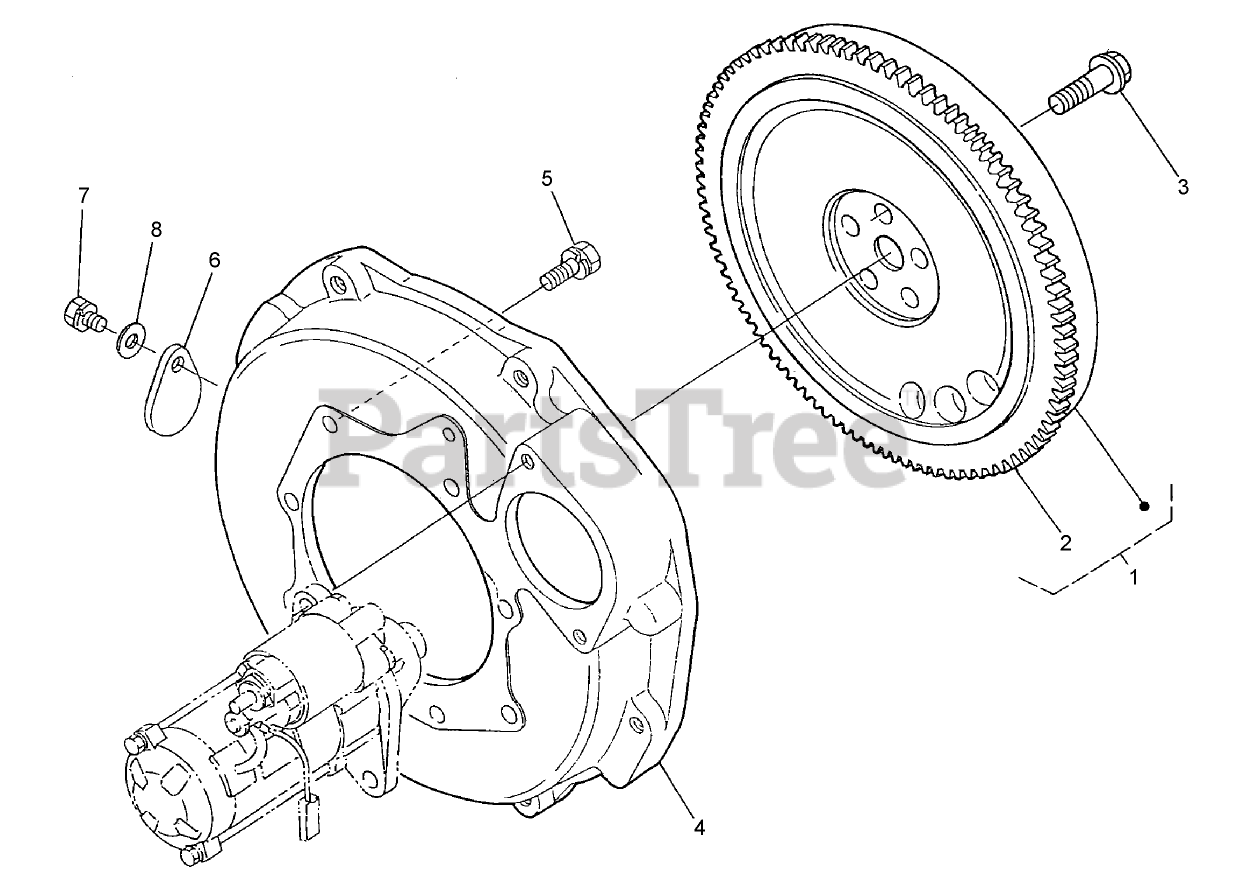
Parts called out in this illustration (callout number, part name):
1	FLYWHEEL ASM
2	GEAR-RING
3	BOLT-FLYWHEEL
4	HOUSING-FLYWHEEL
8	WASHER-PLAIN
